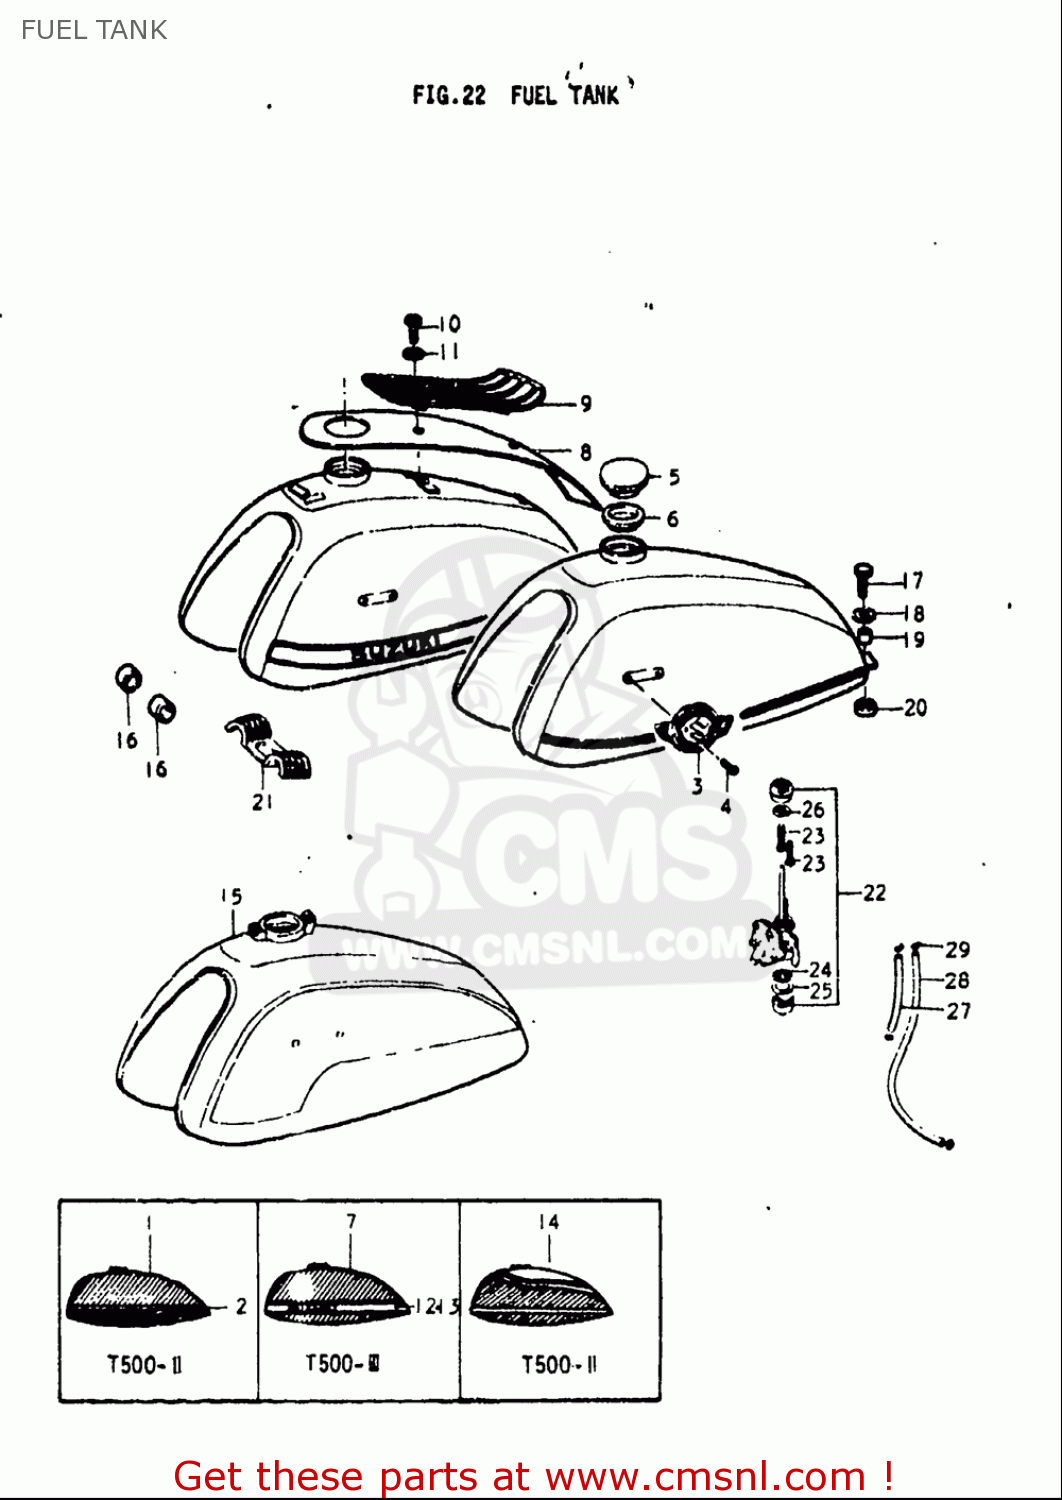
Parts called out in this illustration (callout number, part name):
10	SCREW
11	WASHER,LOCK
16	CUSHION
17	BOLT
19	SPACER(8.5X12X11)
20	BUSH(12X15X20)
22	COCK ASSY,FUEL
25	GASKET,CLEANER CUP (NAS)
26	GASKET,FUEL COCK (NAS)
27	HOSE(5X9X600)
29	CLIP
